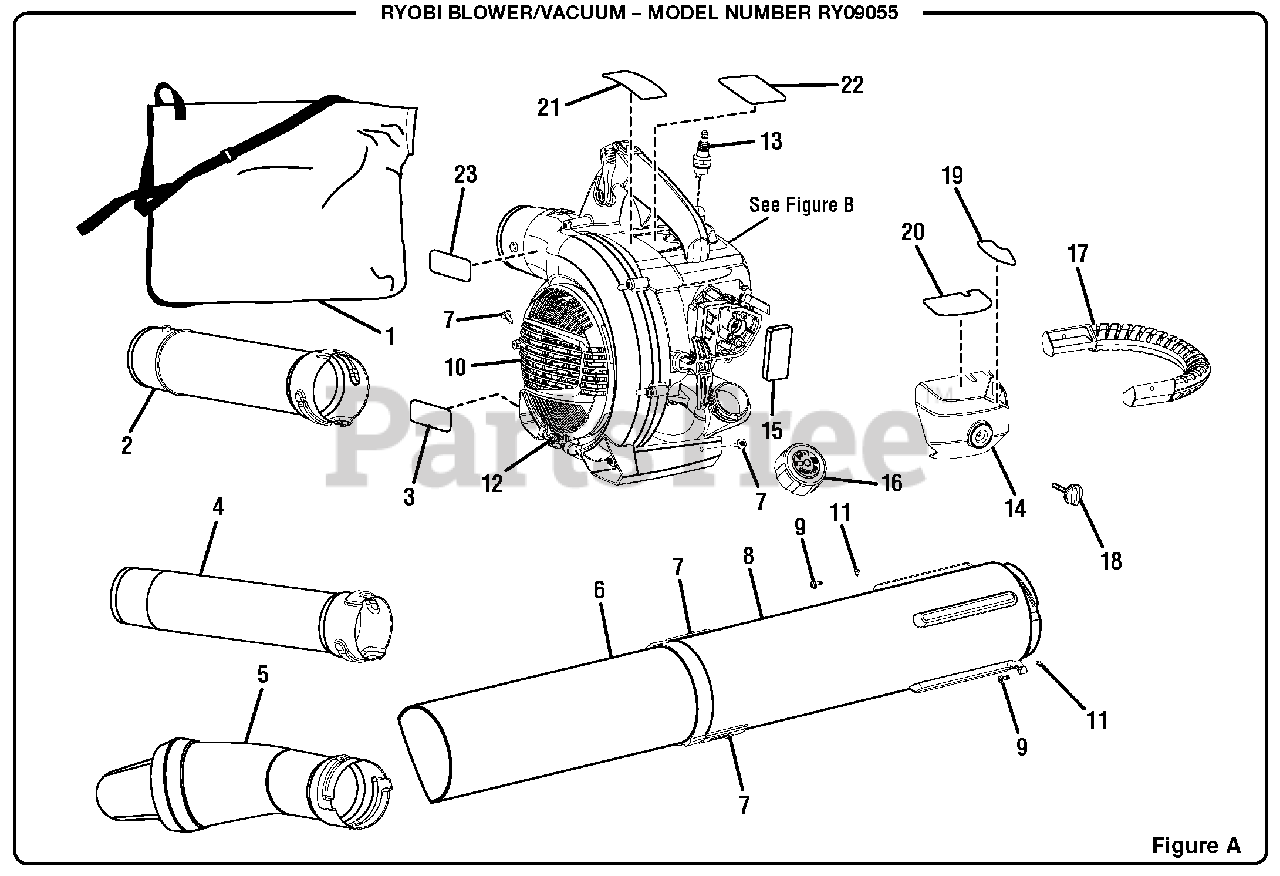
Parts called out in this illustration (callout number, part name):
1	Vacuum Bag w/Shoulder Strap
2	Upper Blower Tube
3	Combustion Label
4	Sweeper Nozzle
5	Vacuum Bag Adaptor
6	Lower Vacuum Tube
7	Vacuum Tube Screw (10-14 x 1/2 in.)
8	Upper Vacuum Tube
9	Screw (1/4-20 x 3/4 in.)
10	Vacuum Door
12	Vacuum Door Spring
13	Spark Plug (RCJ6Y)
14	Air Filter Cover
16	Fuel Cap Assembly
17	Vacuum Handle
18	Knob (Inc. Key No. 18)
19	Choke Label
20	Starting Label
21	Warning Label
22	Logo Label (Small)
23	Logo Label (Large)
